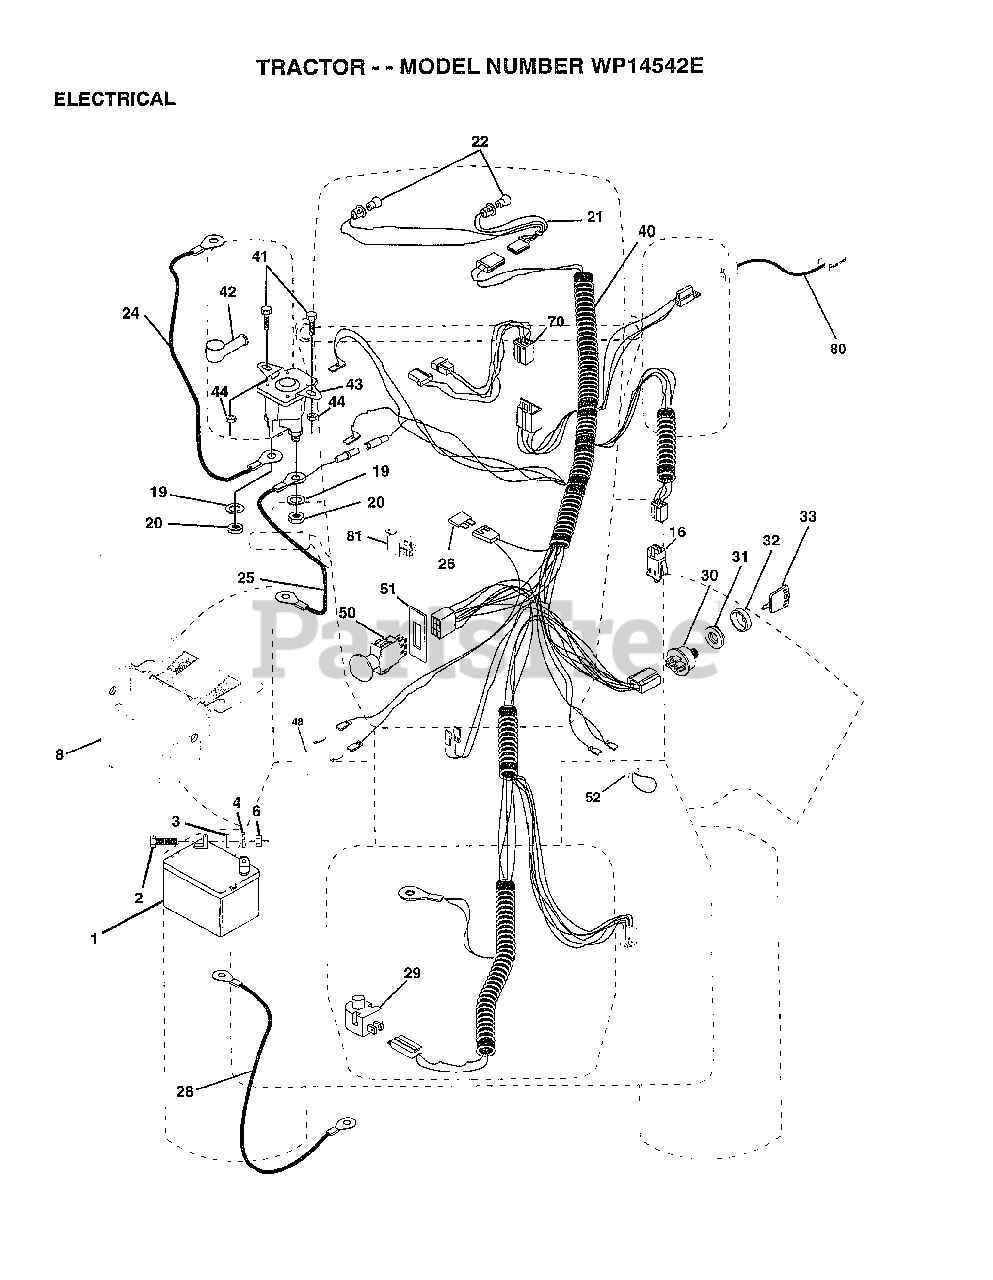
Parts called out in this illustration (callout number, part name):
3	WASHER
4	LOCKWASHER
8	"CASE,BATTERY.MECH"
16	SWITCH INTERLOCK
20	NUT
21	HARNESS.ASM.HDLIG
22	HEADLAMP BULB
24	CABLE.BTRY.6GA.RD
25	CABLE.BTRY.6GA.38
26	FUSE HYT
28	CABLE T
29	SWITCH.PLUNGER
30	SWITCH IGN 4POS
31	NUT IGNITION
32	COVER KEY SWITCH
33	KEY
40	IGNITION HARNESS
41	BOLT HXHD FIN
44	NUT HXKEP 1/4X20
48	ADAPTER AMMETER
50	SWITCH, PTO 3PDT BLACK DELTA 96
51	RING RETAIN PTO
52	PROTECTION LOOP
70	HARNESS.ENG.DUAL
80	HARNESS.CLUT.EVX.
81	RELAY ASSY T
